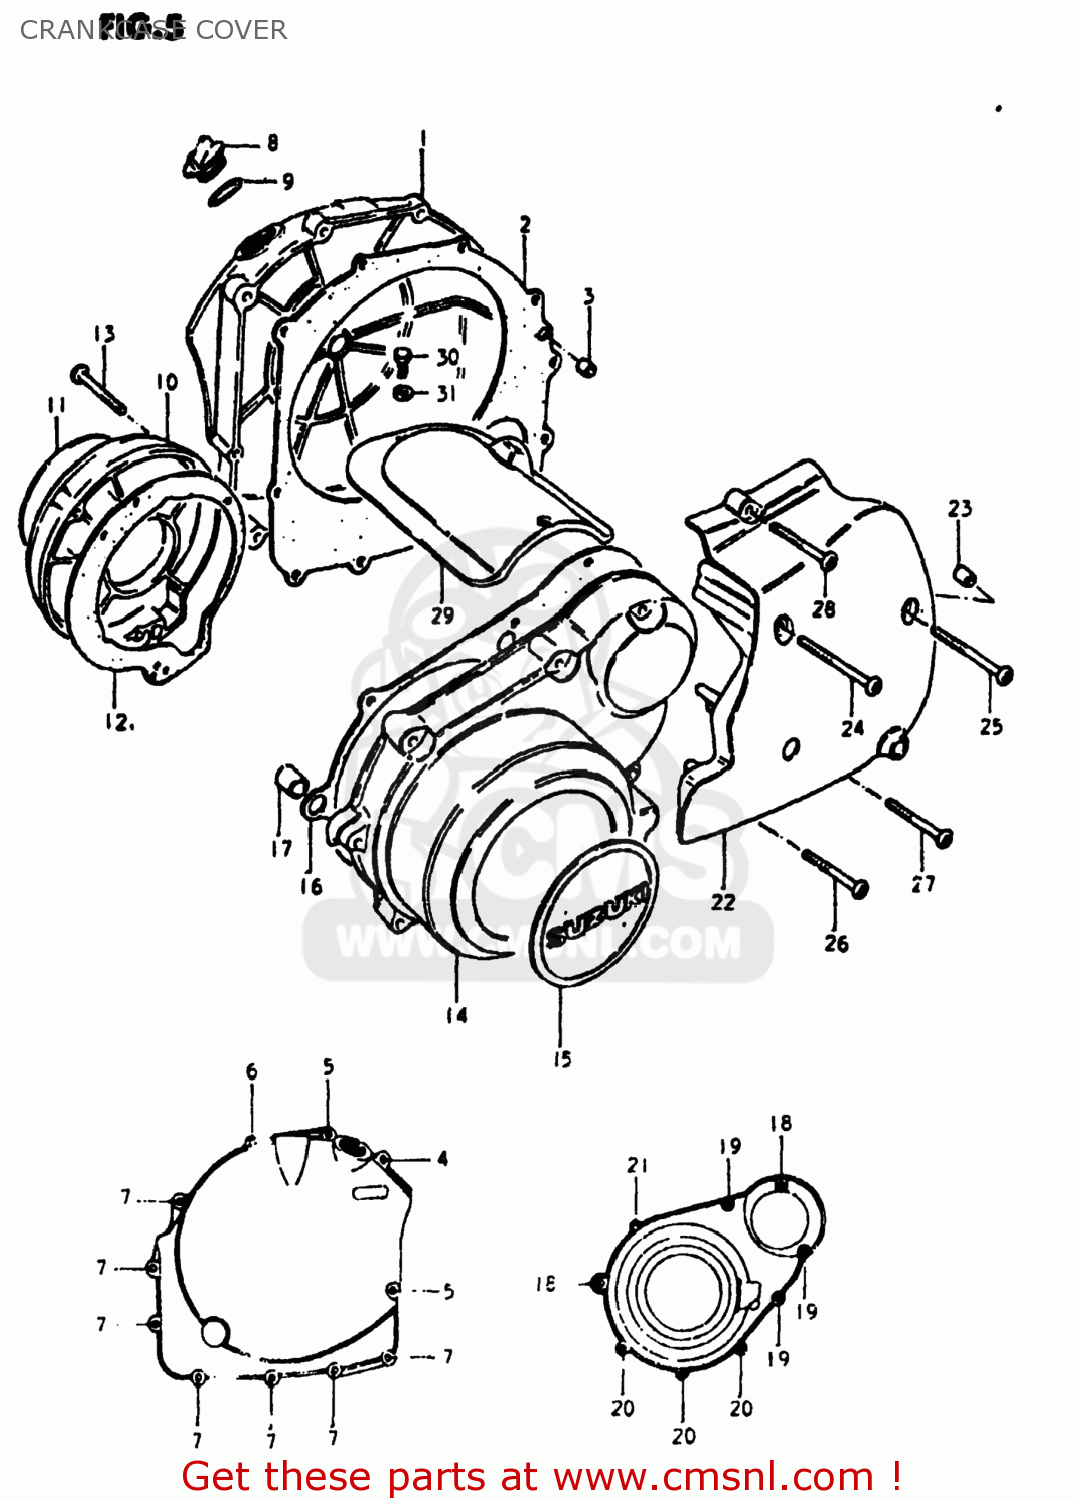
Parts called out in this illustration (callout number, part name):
1	COVER,CLUTCH
2	GASKET,CLUTCH COVER (MCA)
3	PIN
4	SCREW (6X35)
5	SCREW 6X30
6	SCREW
7	SCREW
8	CAP
9	O RING(D:2.2,ID:32)
10	COVER,CONTACT BREAKER
11	EMBLEM
12	GASKET,CONTACT BREAKER COVER (NAS)
13	SCREW
14	COVER
15	EMBLEM
16	GASKET,MAGNETO COVER (MCA)
17	PIN
18	SCREW (6X45)
19	SCREW
20	SCREW (6X35)
21	SCREW 6X30
22	COVER,ENGINE SPROCKET
23	PIN
24	SCREW(6X100)
25	SCREW 6X85
26	SCREW 6X70
27	SCREW
28	SCREW 6X30
29	COVER,STARTER MOTOR
30	BOLT
31	WASHER
